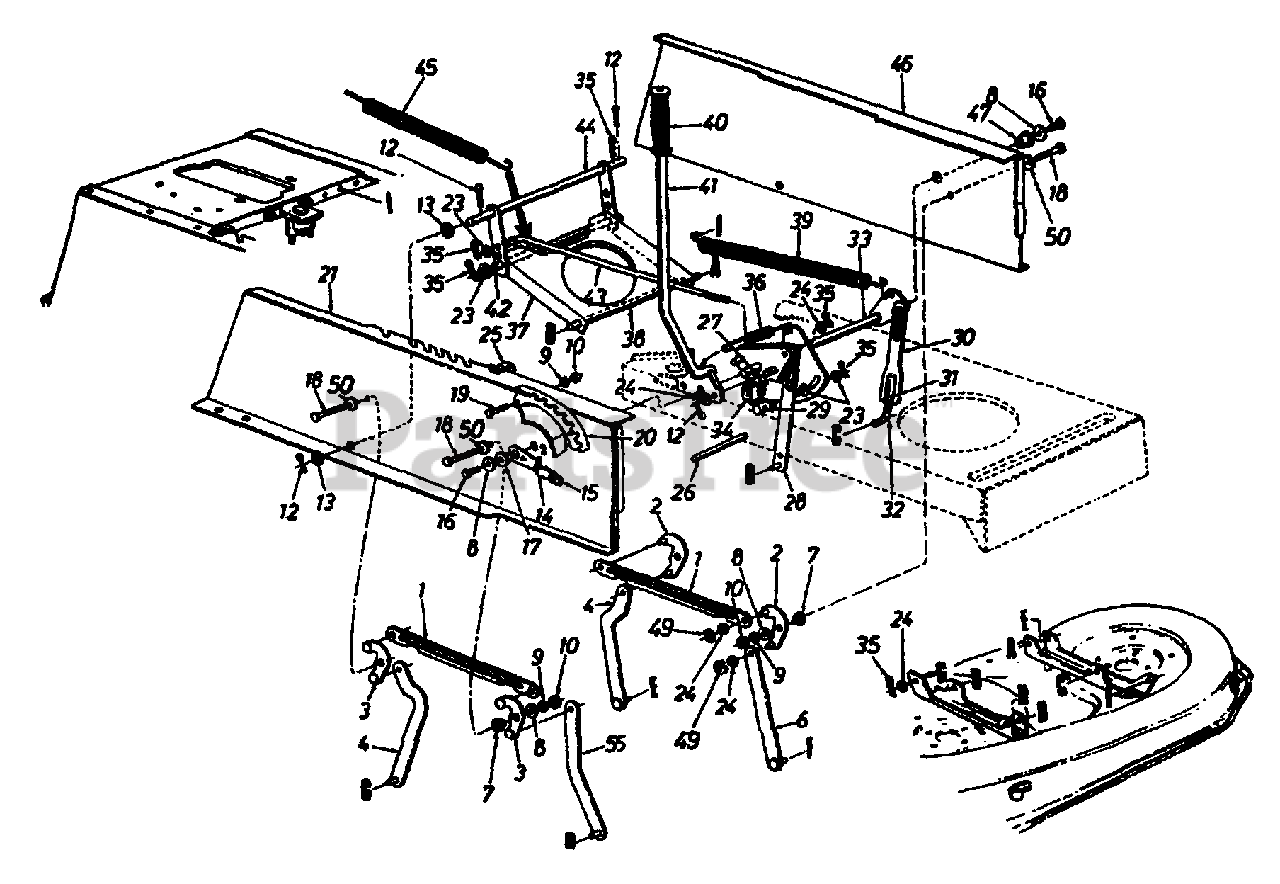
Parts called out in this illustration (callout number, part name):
3	Pivot Link Ass'y.- R.H.
7	Shld. Spacer .318" I.D.
8	R-Wash. .344" I.D. x 1.125" O.D.
9	L-Wash. 5/16" I.D.
10	Hex Nut 5/16-18 Thd. (Gr. 5)
12	Cotter Pin 1/8" Dia.
13	Fl-Wash. .635" I.D. x 1.0" O.D.
14	Hgt Adj. Stop Lever Ass'y. (Ref. 15)
15	Knobs
16	Hex Wash. TT-Tap Scr.5/16-18x.75"
17	Flange Brg. .63" I.D.
18	Hex Wash. Hd. Scr. 5/16-18 x .875"
19	Hex Bolt 5/16-18 x .75" Lg.
20	Index Brkt.
24	Fl-Wash. .531" I.D. x .93" O.D.
25	Clamp
26	Running Board Rod
27	Hex Wash. Hd. Tap Scr.
31	Hex Nut 1/2-20 Thd. (Gr. 5)
32	Lift Link Adjuster
35	Inter. Cotter Pin 3/8" Dia.
36	Extension Spring
39	Extension Spring
40	Grip (Lift Handle)
43	Disengagement Rod
49	"E"-Ring
50	Bell-Wash. .325" I.D.
